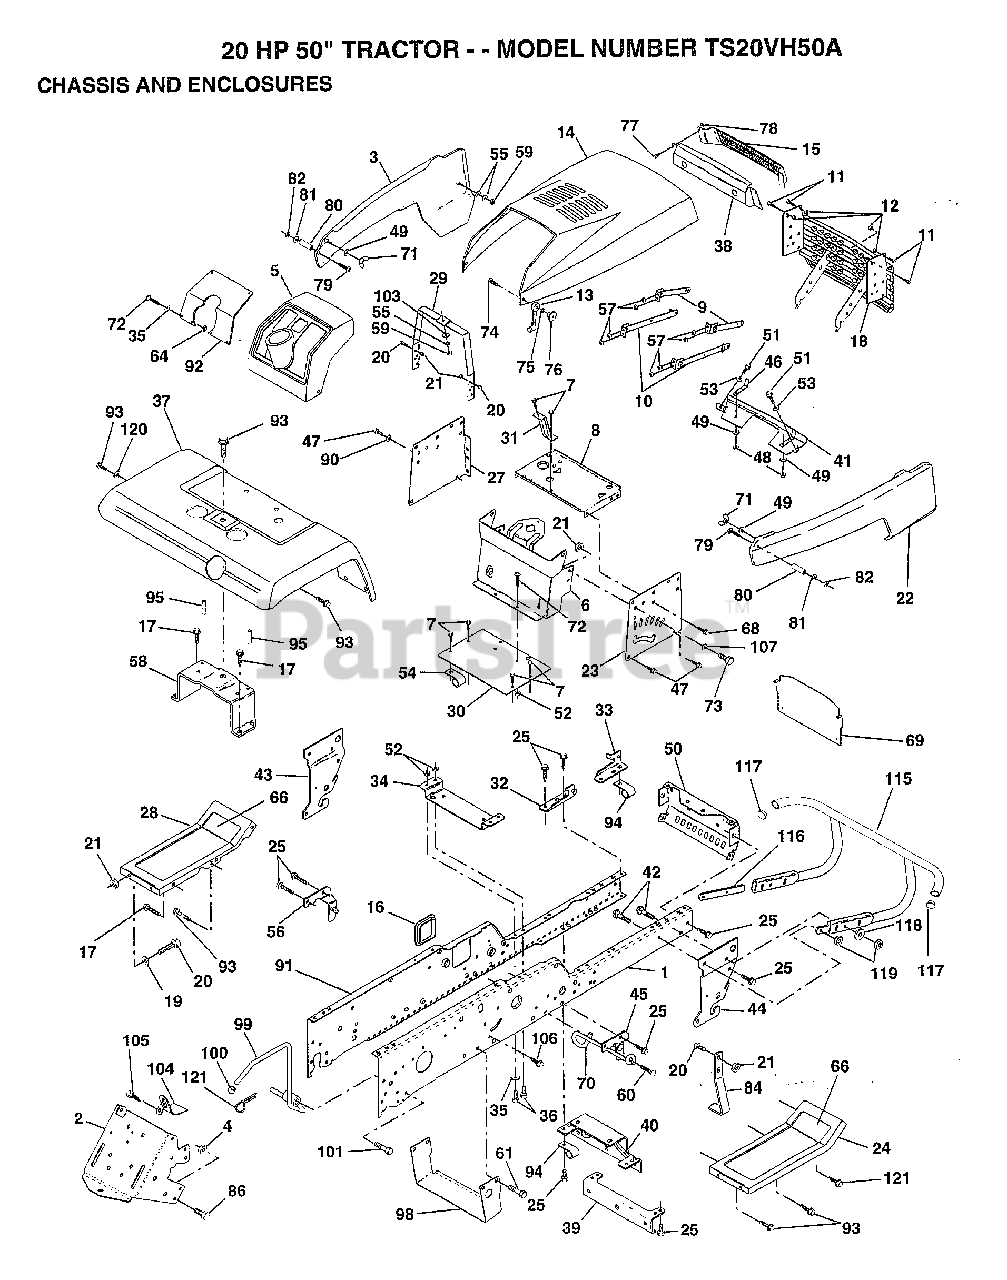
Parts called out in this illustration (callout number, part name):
2	DRAWBAR GT
4	NUT.7/16
5	DASHBOARD BLACK
6	DASH ASM LOWER
7	SCREW
8	SUPPORT BATRY VGT
12	NUT
13	HOOD LATCH T
15	LENS LT
16	COVER ACCESS
17	SCREW
18	GRILLE.ASM.PNT.YP
19	WASHER
20	BOLT
21	NUT
22	PANEL SIDE RH
25	SCREW
26	SCREW
29	SUPPORT ASS'Y
30	SADDLE SLKSCRNED
31	BRACE.SUPT.STRG
32	BRACKET ASM FRAME
33	BRACKET ASM FRAME
34	BRACKET.ENG.SUPT.
35	WASHER
36	BOLT
37	FENDER.PNT.
39	BRACKET.AXLE.FRT.
42	BOLT.3/8-14X1.25
43	BRACKET.SUS.FT.LH
44	BRACKET.SUS.FT.RH
47	SCREW LT
48	SCREW
49	WASHER
50	BRACKET.CHASSIS.
51	SCREW HEX CRT
52	NUT
53	WASHER
54	"CLIP,INSULATOR"
55	WASHER PM
57	NUT
58	BRKT.ASM.FENDER
60	SCREW
61	SCREW
62	RETAINER M
66	FOOTREST PAD
68	SCREW LT
69	SHIELD.HEAT.VGT.
70	GUIDE.BELT.MID.SP
72	SCREW
73	BOLT
74	SCREW
75	LOCKWASHER
76	WELDNUT
78	"""J"" FASTENER LT"
79	SCREW
80	SPACER LT
81	WASHER
84	STOP.OVER.CENTER
86	BOLT
90	LOCKWASHER
92	PLATE YP SLKSCR
93	SCREW LT
94	CLIP GTV
95	NUT-PUSH YT
98	BRACKET SKID CHAS
99	ROD BYPASS
101	SCREW LT
103	LOCKWASHER
104	LOCK BYPASS BRKT
105	SCREW LT
106	BOLT.5/16-18X1.25
107	WASHER
115	BUMPER.ASM.W/PY
116	BRACKET.EXT.BUMP.
117	PLUG.PLASTIC
118	WASHER
120	WASHER HYT
121	SCREW GTV
